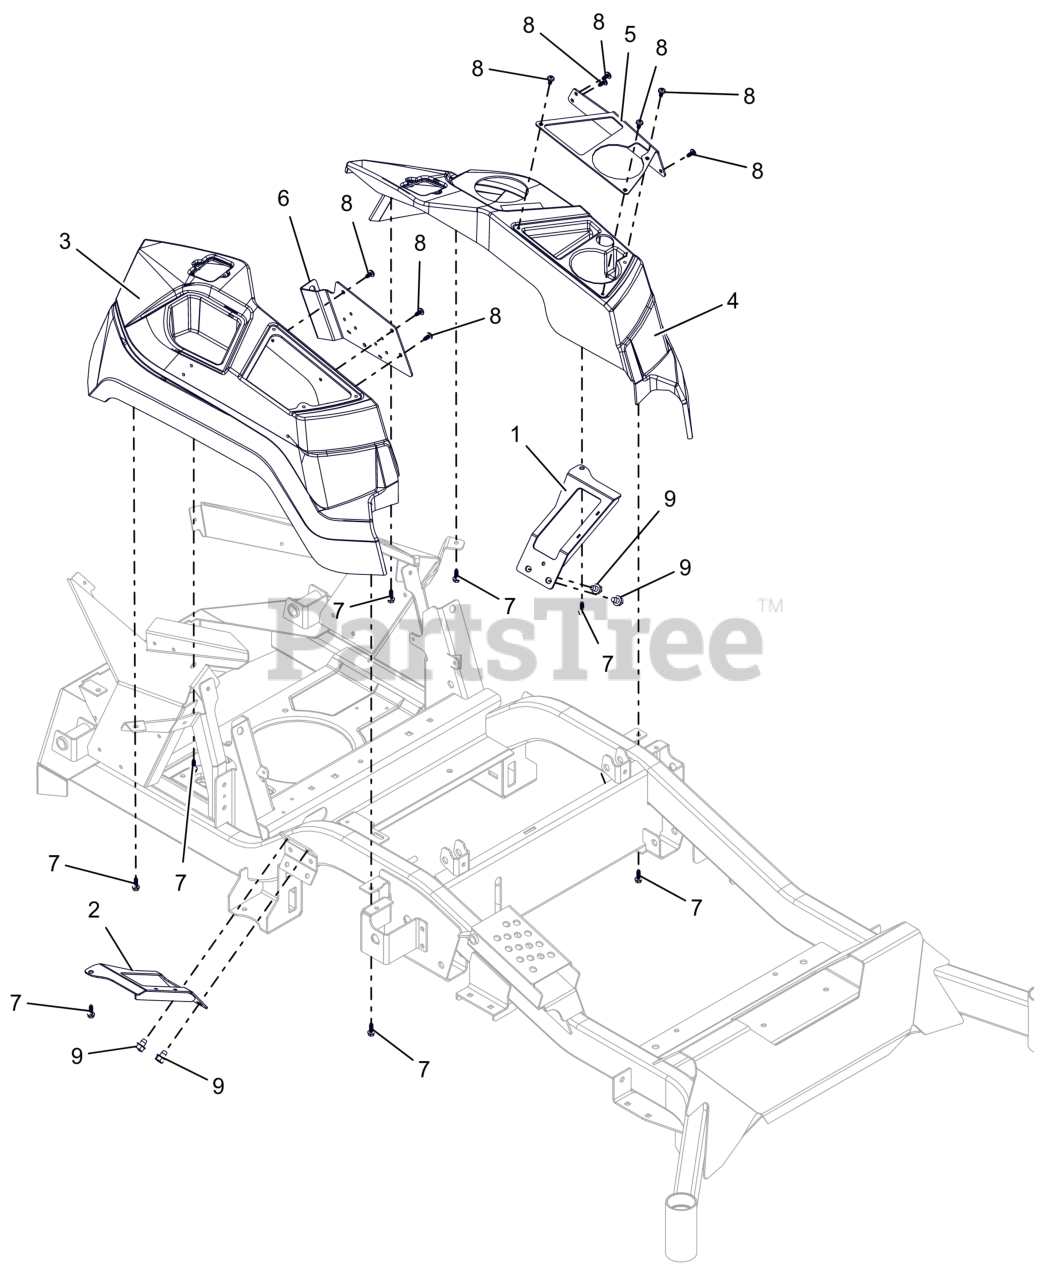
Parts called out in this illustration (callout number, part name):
1	WLDMT, LH FENDER MOUNT
2	WLDMT, RH FENDER MOUNT
3	FENDER, RH APEX - 2017
4	FENDER, LH APEX
5	PLATE, APEX CUP HOLDER COVER
6	BRKT, FENDER/RELAY MOUNTING
7	SCR, PLASTITE .25-10X.75 ZCC
8	SCR-PAN .25-15X.50 6L H/LZB500
9	SCR,TAP .375-16X.50 HWH TR ZCC
